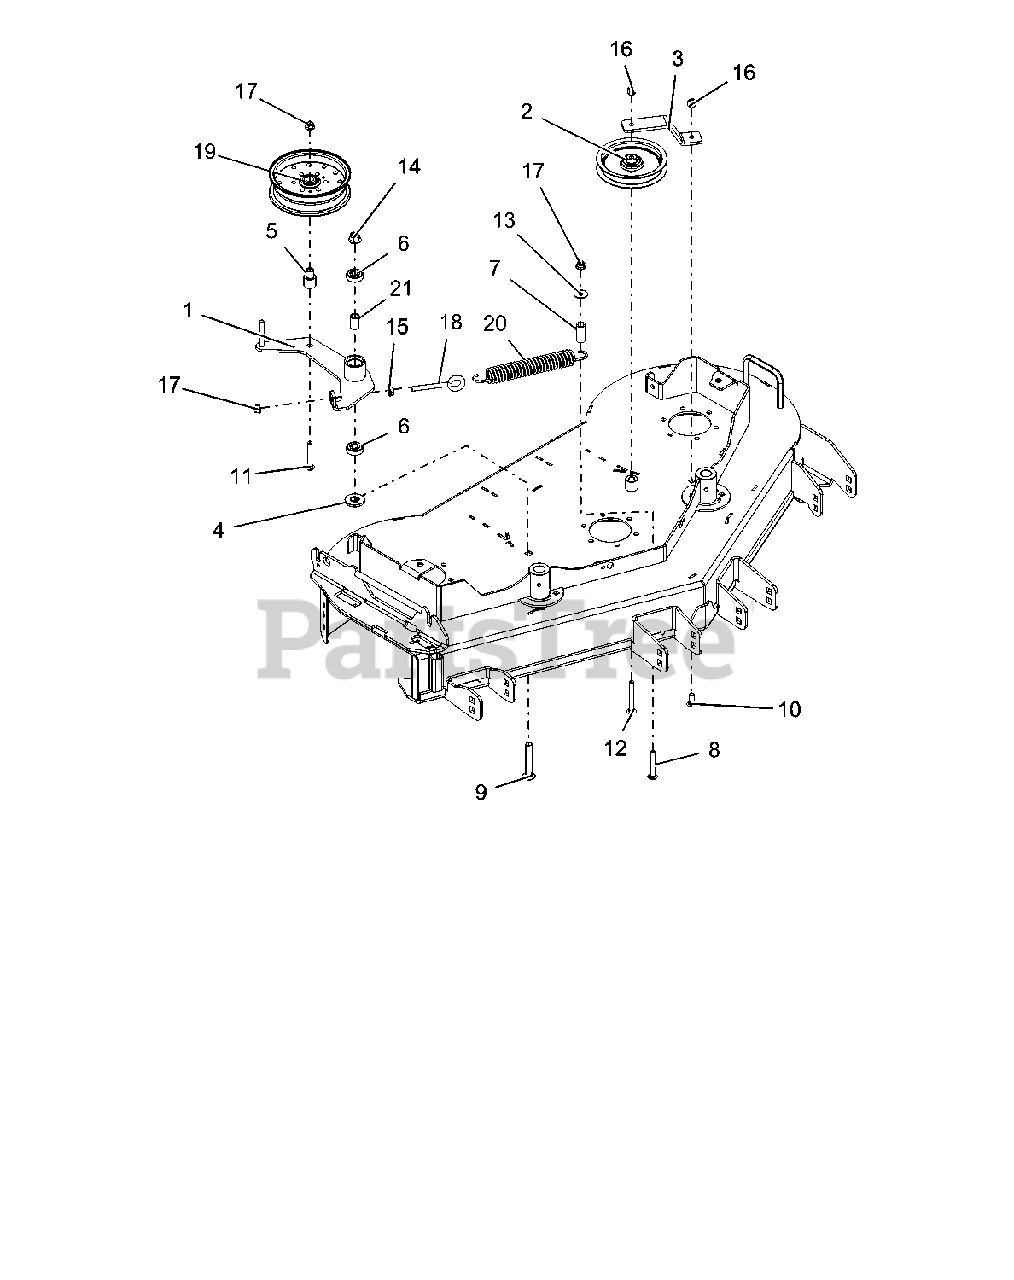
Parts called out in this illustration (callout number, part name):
1	WLDMT, IDLER ARM 52/48 FLWLK (BLACK)
2	IDLER, FLAT - 5.00" X .75"
3	STRAP, IDLER 48/52 WALK-BLACK
4	SPACER, IDLER ARM
5	SPCR, IDLER
6	BRG-BALL .500X1.375X.44
7	BSHG-SLV .500X.750X1.560
8	BLT-RHDSSQNK .38-16X2.50 G5YZ
9	BLT-RDHDSQSHNK .50-13X3.25 YWZC
10	BLT-RDHDSHSQNK.38-16X1.0 G5YZ
11	BLT-RDHDSQNK .38-16X2.50 G5 Y
12	BLT-RDHDSQNK .38-16X3.00 G5 YWZC
13	WSHR-FL-STL .375X1.125X.065YWZ
14	NUT-LK-NYL-FLG .50-13 YWZC
15	@NUT-SPNLK-FLG .375-16 YWZC
16	NUT-LK-NYL .38-16 YWZC
17	NUT-LK-NYL-FLG .38-16 YWZC
18	BOLT, EYE .38-16X4.50 .75 DIA
19	PULLEY, FLAT IDLER 6.00 X .635
20	SPRG, EXTENSION
21	SPACER, .510 X .750 X 1.148
